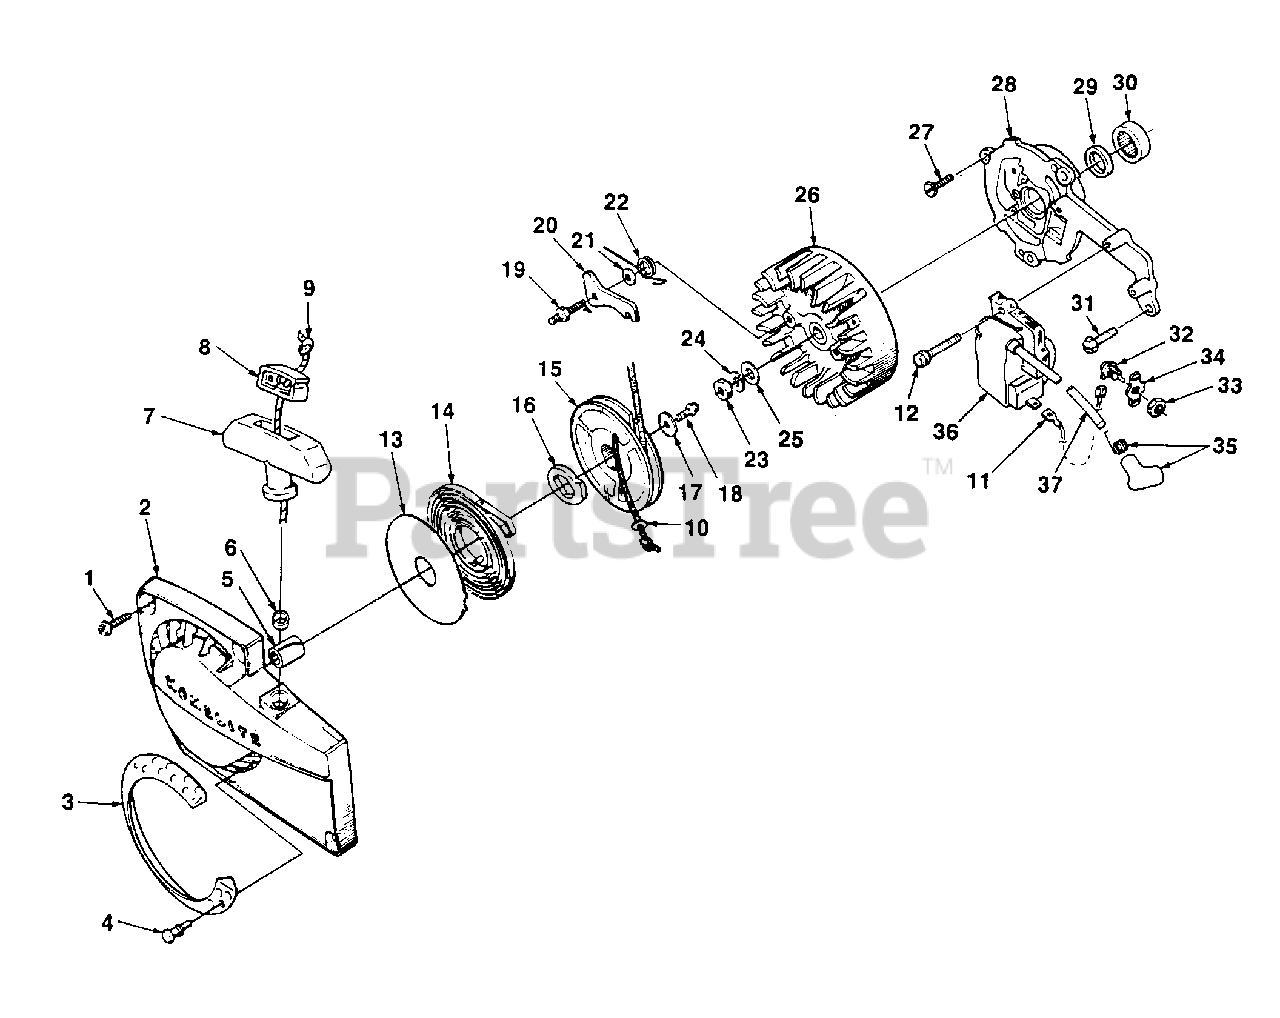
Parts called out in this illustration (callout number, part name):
1	SCREW-Hex hd. 12-24 x 5/8
2	HOUSING-Starter
3	KIT-Fan housing screen
4	STUD-Drive #2 x 1/4
5	BUSHING
6	BUSHING
7	GRIP-Starter
9	ROPE-Starter (48", #5)
11	LEAD-Ground
12	SCREW-Sems hex hd. 8-32 x 1
15	PULLEY & CUP
16	LOCK-Spring
18	SCREW-Hex hd. 10-32 x 1/2
19	STUD-Starter pawl
20	STARTER PAWL
21	WASHER-Flat
22	SPRING-Starter pawl
23	NUT-Hex 3/8-24
24	WASHER-Lock 3/8
25	WASHER-Flat 3/8
26	ROTOR-Magneto
27	SCREW-Hex 1/4-20 x 5/8
28	PLATE-Back
29	SEAL
30	BEARING-Roller
31	SCREW-Sems hex hd. 1/4-20 x 3/4
32	SWITCH
33	NUT
34	PLATE-Indicating
35	TERMINAL-Spark plug
36	MODULE-Ignition
37	LEAD-High tension
